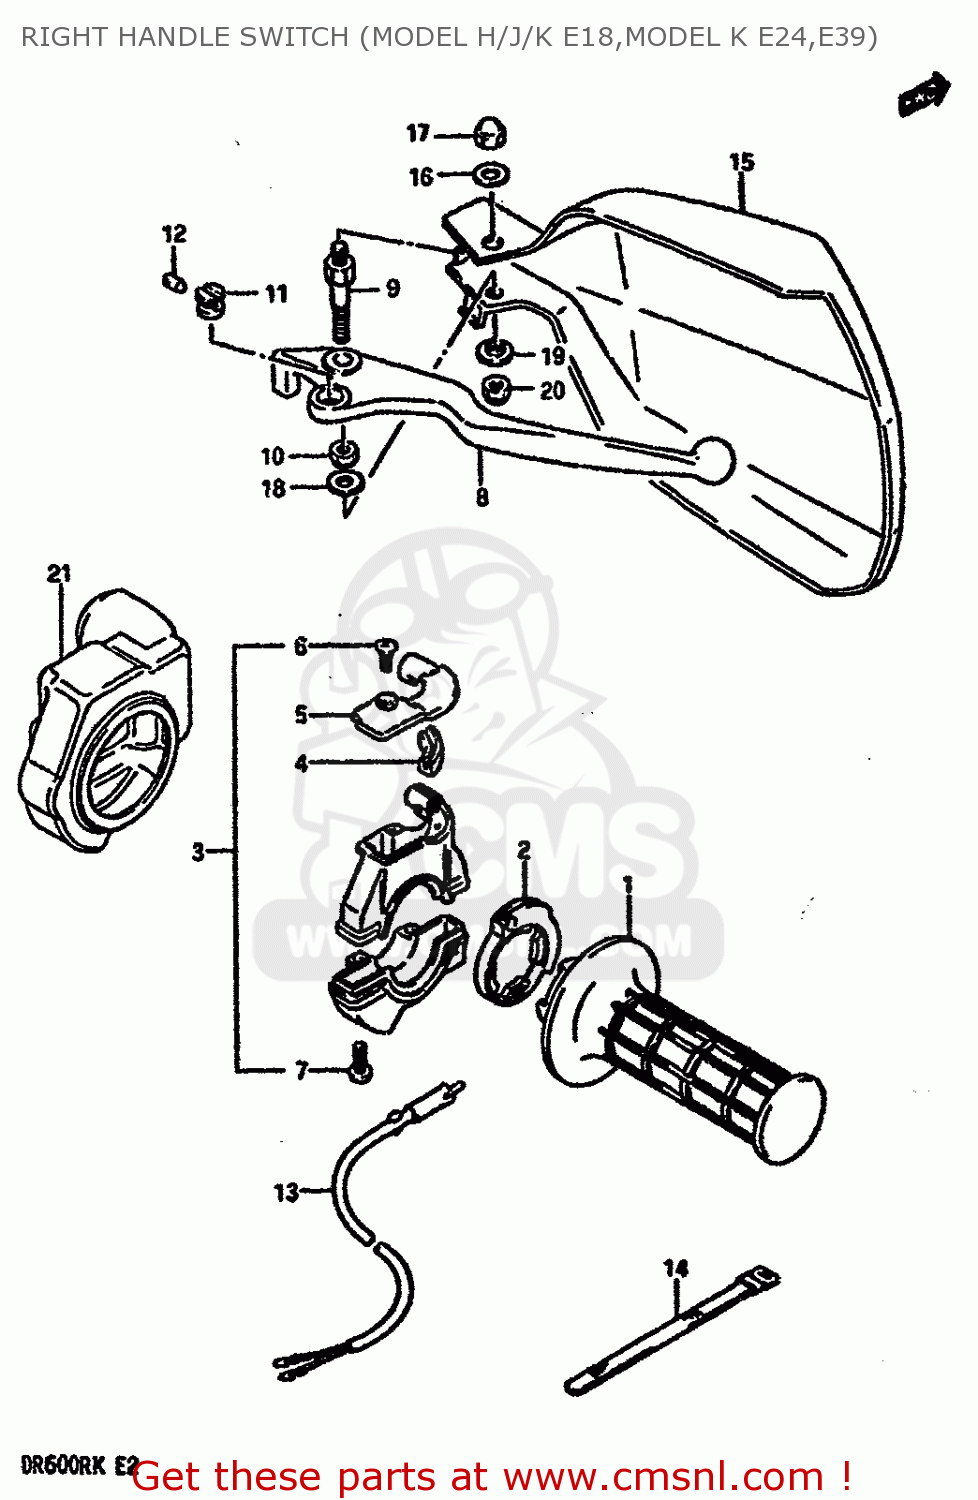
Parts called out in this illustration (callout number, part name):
1	GRIP,THROTTLE
2	ROTOR,THROTTLE GRIP
3	CASE ASSY,THROTTLE
4	GUIDE PIECE,THROTTLE
5	COVER,THROTTLE CASE
6	SCREW
7	SCREW
8	LEVER,BRAKE
9	BOLT,BRAKE LEVER PIVOT
10	NUT
11	ADJUSTER
12	ROD,PUSH
13	SWITCH ASSY,STOP
14	CLAMP(L:120)
15	COVER,KNUCKLE RH (WHITE)
16	WASHER (6.5X20X1.6)
17	NUT 6MM
18	WASHER(6.5X16X1.2)
19	WASHER
20	NUT 6MM
21	COVER,THROTTLE CASE
